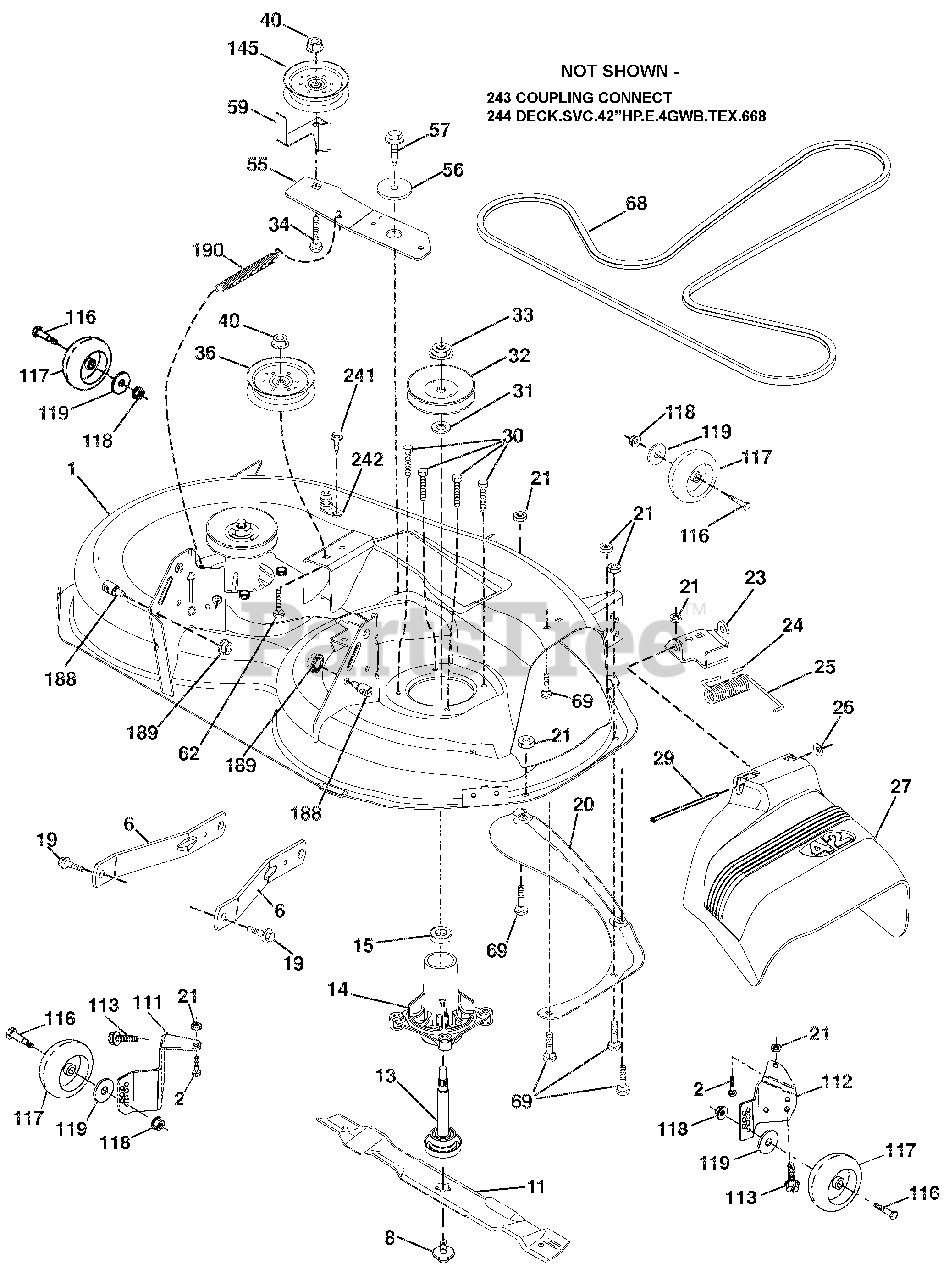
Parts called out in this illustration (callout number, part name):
1	MOWER HOUSING
6	ARM.SUSPENSION.MOWER.REAR.LD
8	BOLT/WASHER ASM.7/16-20.UNF
11	BLADE.MOWER.42"HI LIFT PREMIUM
11	Blade 42SP" 3N1
11	Blade 42SP" 3N1 Premium
11	BLADE, HUSQ MULCH KIT
11	Blade Mulching 42 Premium (Fo
13	SHAFT ASM.MNDRL.N/GREASEABLE38
14	HOUSING.MANDREL.4PT.SERVICE
15	BEARING.BALL.MANDREL
19	BOLT.SHOULDER
20	BAFFLE.VORTEX.42.STD/HEAVY DTY
21	Nut, Hex, Crownlock 5/16-18
23	BRACKET.DEFLECTOR.38/42"2005
24	CAP.SLEEVE..80X.112.BLK.MOWER
25	SPRING.TORSION.DFL.38/42/46.GR
26	NUT.PUSH.PHOS.& OIL
27	SHIELD.DEFLECTOR.
29	ROD.HINGE.42/46"
30	SCREW.THD ROLL.DOD PT.HEX
31	WASHER.SPACER.MANDREL
32	MANDREL.PULLEYS.42,44,50
32	MANDREL ASM.SUB.N-GRS.4 BOLT
32	PULLEY/NUT/WASH-ER AND BLADE BOLT/WASHERS NOT INCLUDED)
33	NUT.FLANGE.LOCK.TOP
34	BOLT.CARR.SH.3/8-16X1-1/2.GR5
36	PULLEY.IDLER.4.50.RAW
40	Nut, Hex, Flangelock 3/8-16
55	IDLER.ARM
56	SPACER.RETAINER
57	SCREW.3/8-16X1.SMGML.TAP/R.BLK
59	GUARD.TUV.IDLER
62	BOLT.RD.HD.SQ.NK.3/8-16UNC X 2
68	V-Belt, 42" Mower
69	BOLT.RDHD.SQNK.5/16-18 X 5/8
111	BRACKET WHEEL GAUGE LH
112	BRACKET WHEEL GAUGE RH
113	BOLT.5/16-18HEX.WHS.HD.LCKSERR
116	BOLD SHLD "A" 2.41 "B" 1.66
117	WHEEL.GAGE.HALF.SPOKED
118	Nut, Hex, Flangelock 3/8-16
119	Washer 3/8 x 7/8 x 14 Ga.
145	PULLEY.IDLER 48"PRIMARY
188	STUD.FASTNER.W/'D'ANTI-ROTATIO
189	Nut, Lock Hex Flange 5/16-18 u
242	PORT WASHOUT
